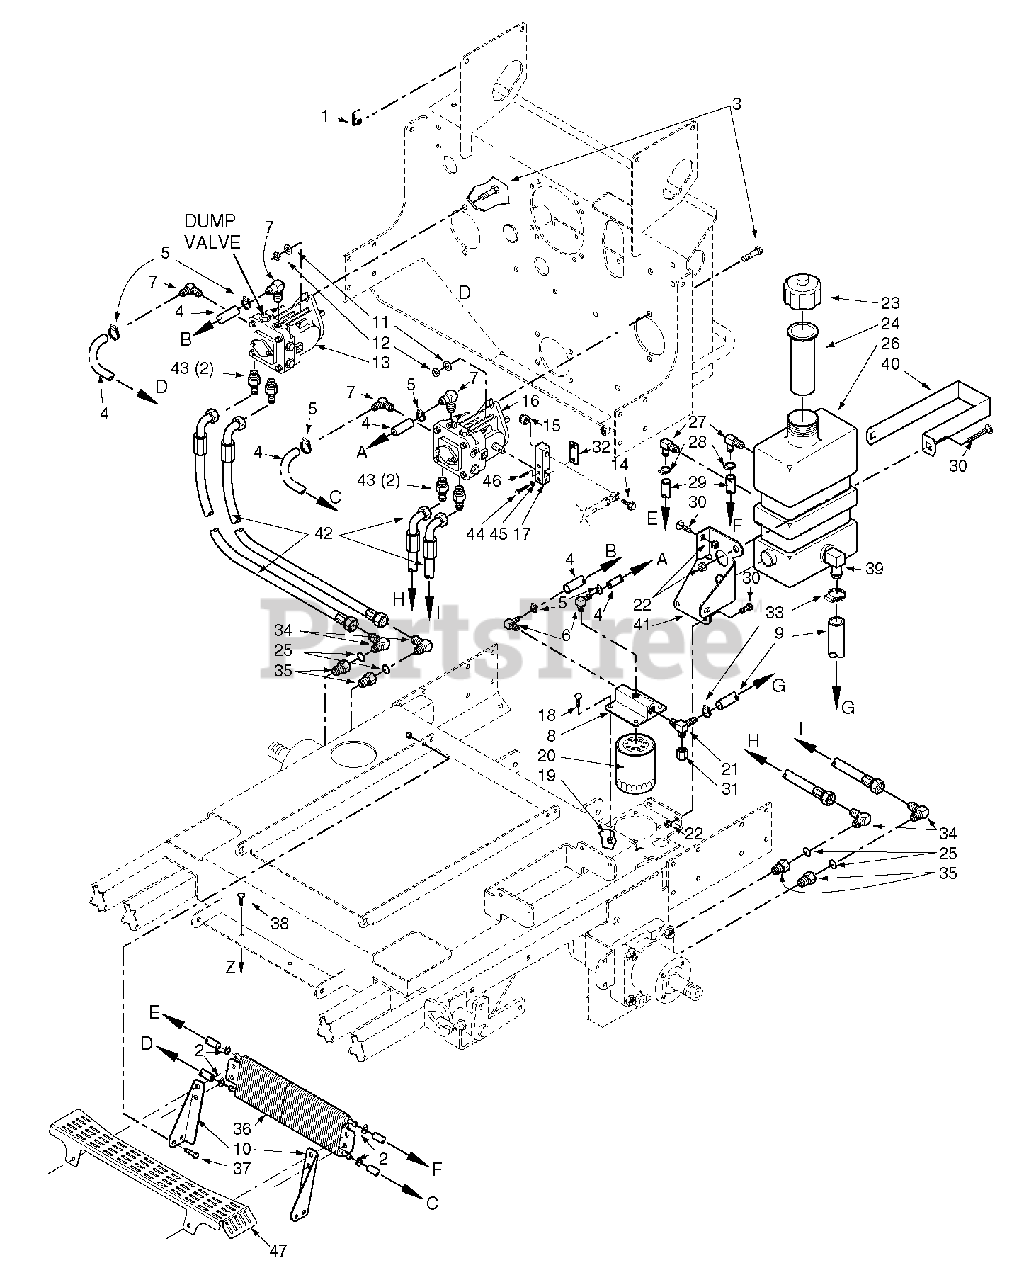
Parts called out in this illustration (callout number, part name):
1	U-Nut 1/4-20
2	Hose Clamp, 0.69" Dia.
3	Bolt, Hex Head 1/4-20 x 2.0"
4	Hose, 3/8" ID Pushlock - (order by inch)
5	Clamp, Hose 1/2"
6	Elbow, 90 Degree - 1/4" NPT x 3/8" Hose
7	Elbow, 90 Degree - 9/16" O-Ring x 3/8" Hose
8	Oil Filter Base
9	Hose Assembly, 1/2" ID (Tank to Filter Base)
10	Mounting Bracket - LH, Oil Cooler
10	Mounting Bracket - LH, Oil Cooler (35BVAC)
10	Mounting Bracket - RH, Oil Cooler
10	Mounting Bracket - RH, Oil Cooler (35BVAC)
11	Flatwasher, 3/8" (.391 x .938 x .105")
12	Nut, Hex Elastic Stop 3/8-16
13	Pump, Right Hand
13	Pump w/Fan, Right Hand (26DFI, 35BVAC)
14	Bolt, Hex Head, 3/8-16 x 1-1/4"
15	Nut, Hex, Elastic Stop 3/8-16
16	Pump, Left Hand
16	Pump w/Fan, Left Hand 26DFI, 35BVAC)
17	Block, Pump Control
18	Bolt, Hex Head 5/16-18 x 1.0" Zinc
19	Nut, Serrated Flange 5/16-18
20	Oil Filter
21	Tee, 3/4" O-Ring x JIC x 1/2" Hose
22	Nut, Hex Elastic Stop 1/4-20
23	Cap, Hydraulic Tank
24	Insert, Filler Neck
25	O-Ring
26	Oil Reservoir Assembly
27	Elbow, 90 Degree .38" Hose
27	Bushing, .56" Dia. Viton
28	Hose Clamp, 0.69" Dia.
29	Hose, 3/8" ID, Pushlock (order by inch)
30	Screw, Phillips Head, 1/4-20
32	Clamp Plate, Pump Control
33	Clamp, Hose
34	Elbow, 90 Degree, 1/2" x 1/2" (35BV Only)
34	Elbow, 90 Degree, 5/8" x 1/2"
35	Bushing, 7/8"-14 JIC x 3/4"-16 O-Ring
36	Cooler, Oil
37	Bolt, Hex Head 5/16-18 x 3/4"
38	Bolt, Carraige 1/4-20 x 3/4"
39	Elbow, 90 Degree
39	Bushing, .78" Dia. Viton
40	Strap, Hydraulic Tank
41	Support Bracket, Hydraulic Tank
42	Hose Assembly, Pump
43	Union, 3/4"-16 JIC x 3/4"-16 O-Ring
44	Bolt, Hex Head, 1/4-20 x 1-1/4"
45	Lockwasher, 1/4" Spring
46	Roll Pin, Spring 3/16 x 3/4"
47	Screen Guard, Kohler Engine
47	Screen Guard, BVAC Engine
